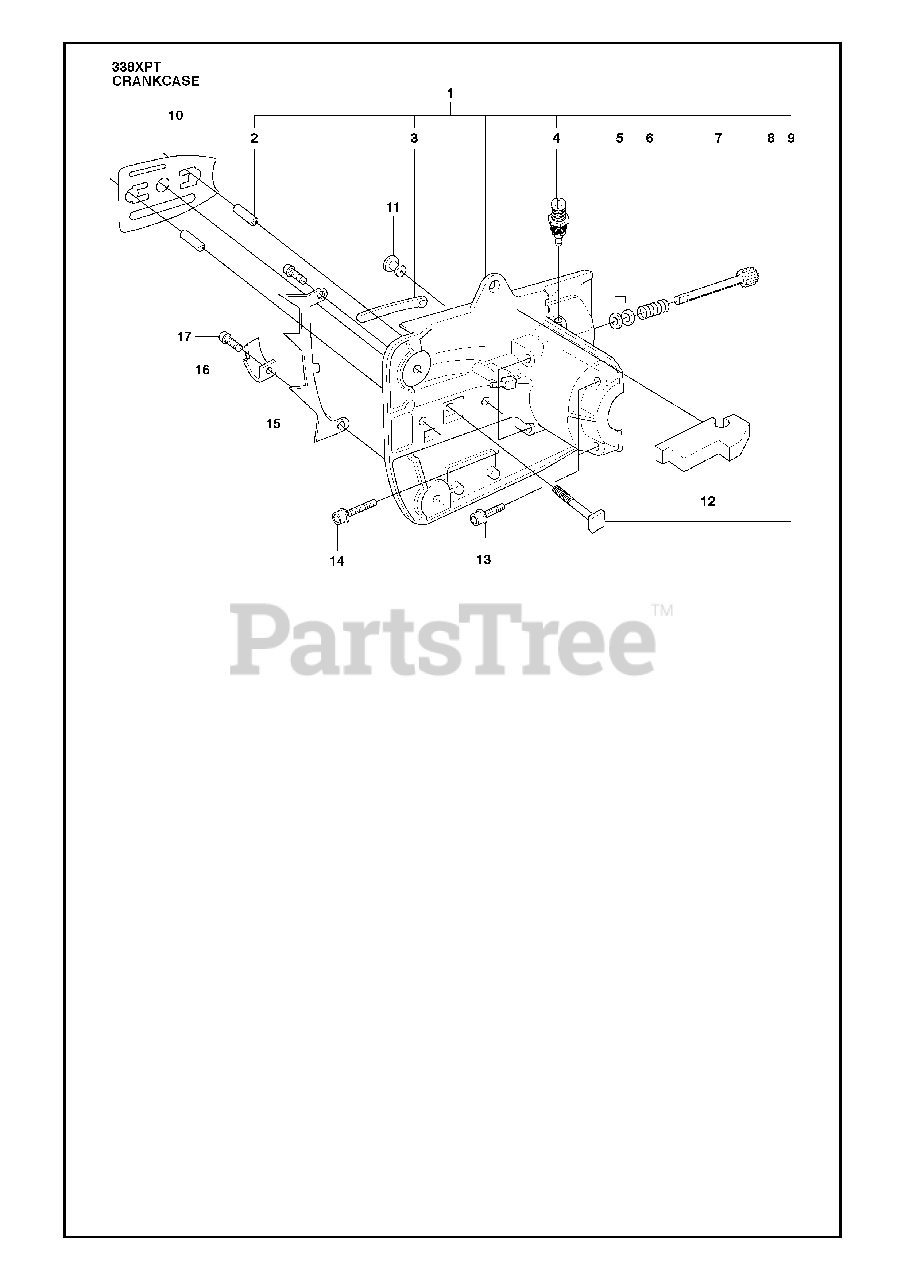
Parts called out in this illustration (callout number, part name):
2	GUIDE BAR LOCATING PIN
4	INSERT OIL PUMP
5	WASHER 5.1X8.5
7	PUMP PISTON
10	CHAIN GUIDE PLATE
12	FOAM INSULATOR
15	FELLING DOG
16	CHAIN CATCHER
